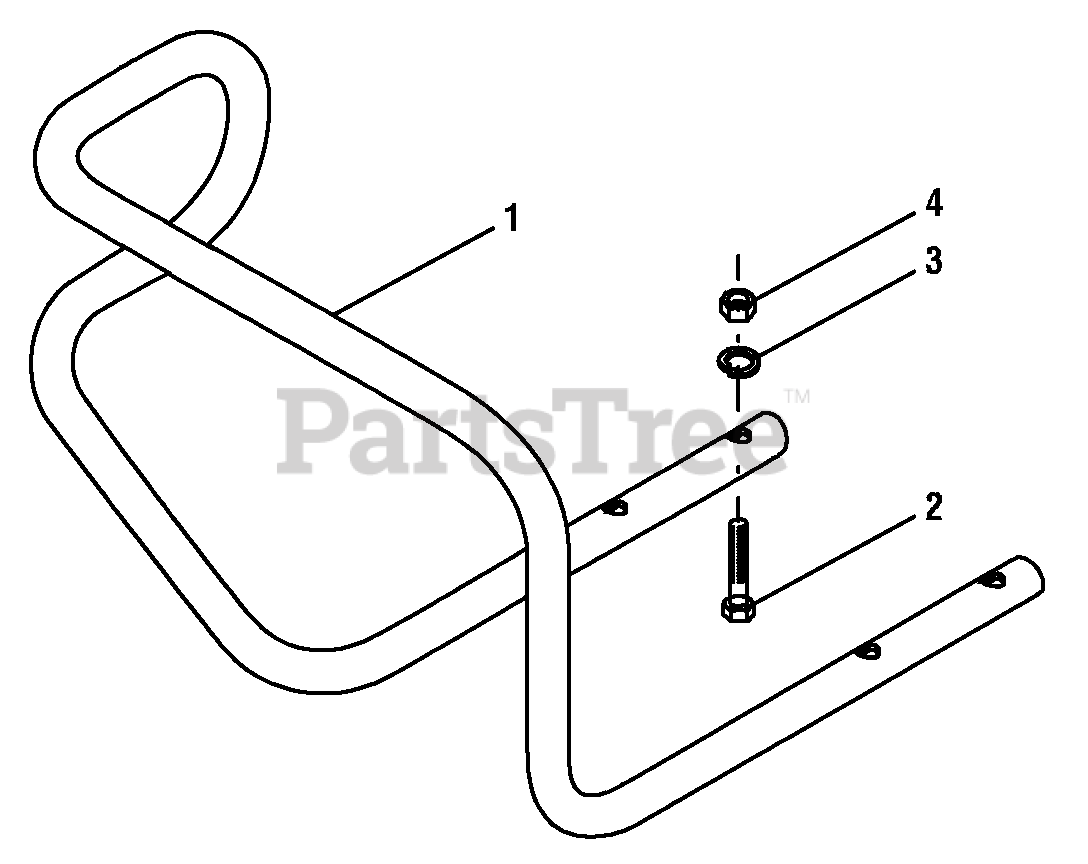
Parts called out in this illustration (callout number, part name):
2	Hex Screw, 5/16-18 x 2-1/4, Gr5
3	Nut, Hex, 5/16-18
4	Lock Washer, 5/16
